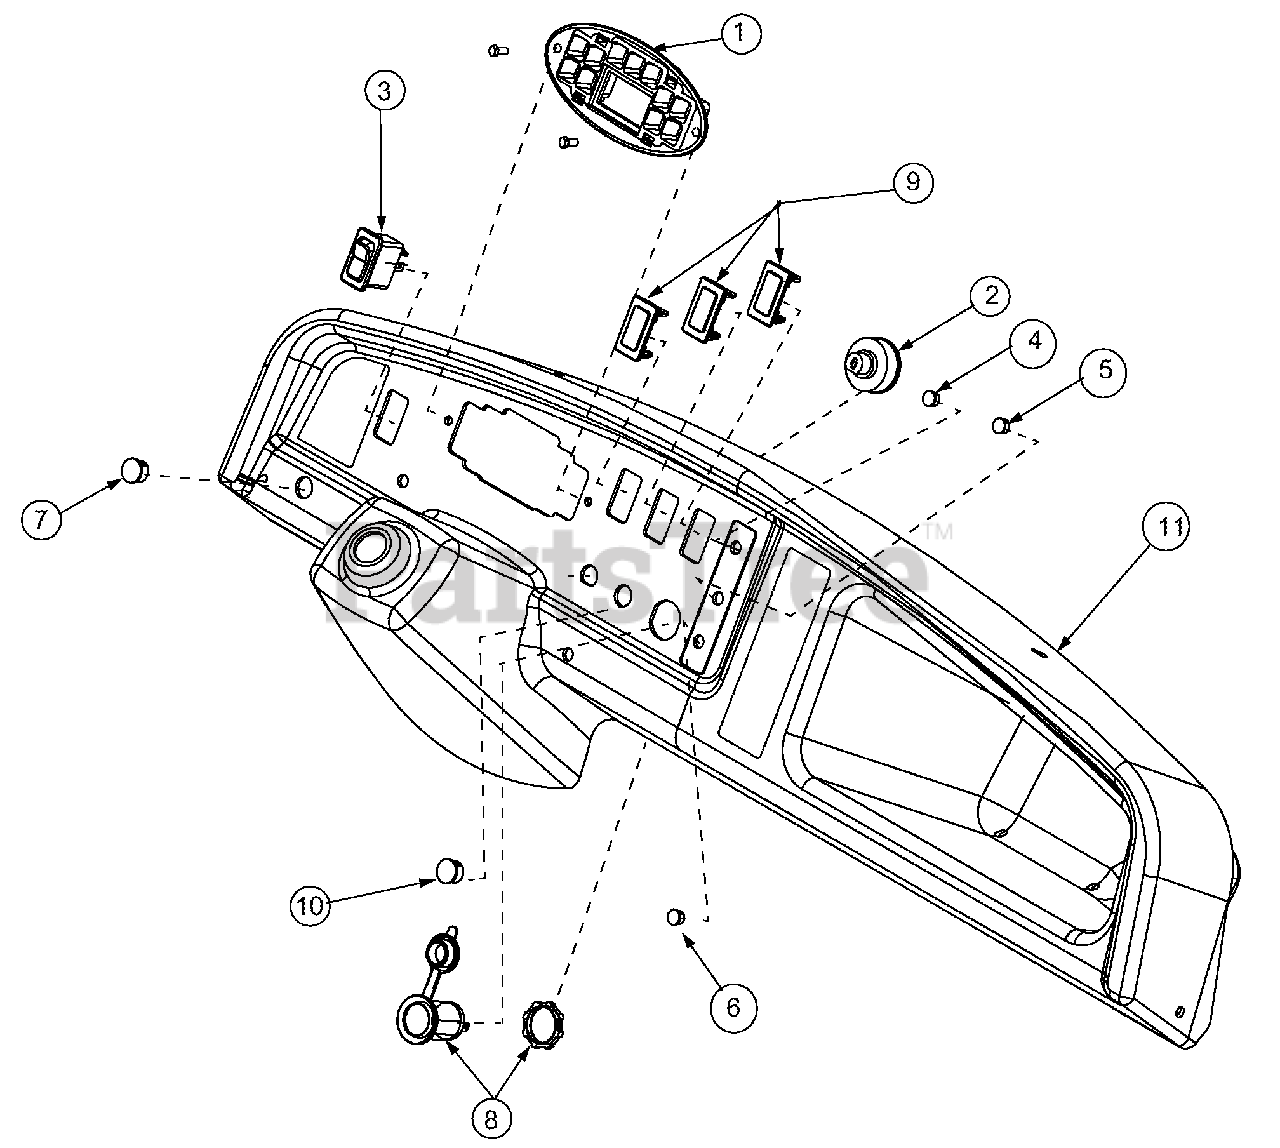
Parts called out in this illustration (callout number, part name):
1	Instrument Panel
2	Switch, Key
3	Rocker Switch, Headlight
4	Switch, Green
5	Switch, Yellow
6	Switch, Red
7	Switch, Diff-Lock
8	Receptacle, Power, 12v
10	Plug, Horn Switch
11	Dash Panel
